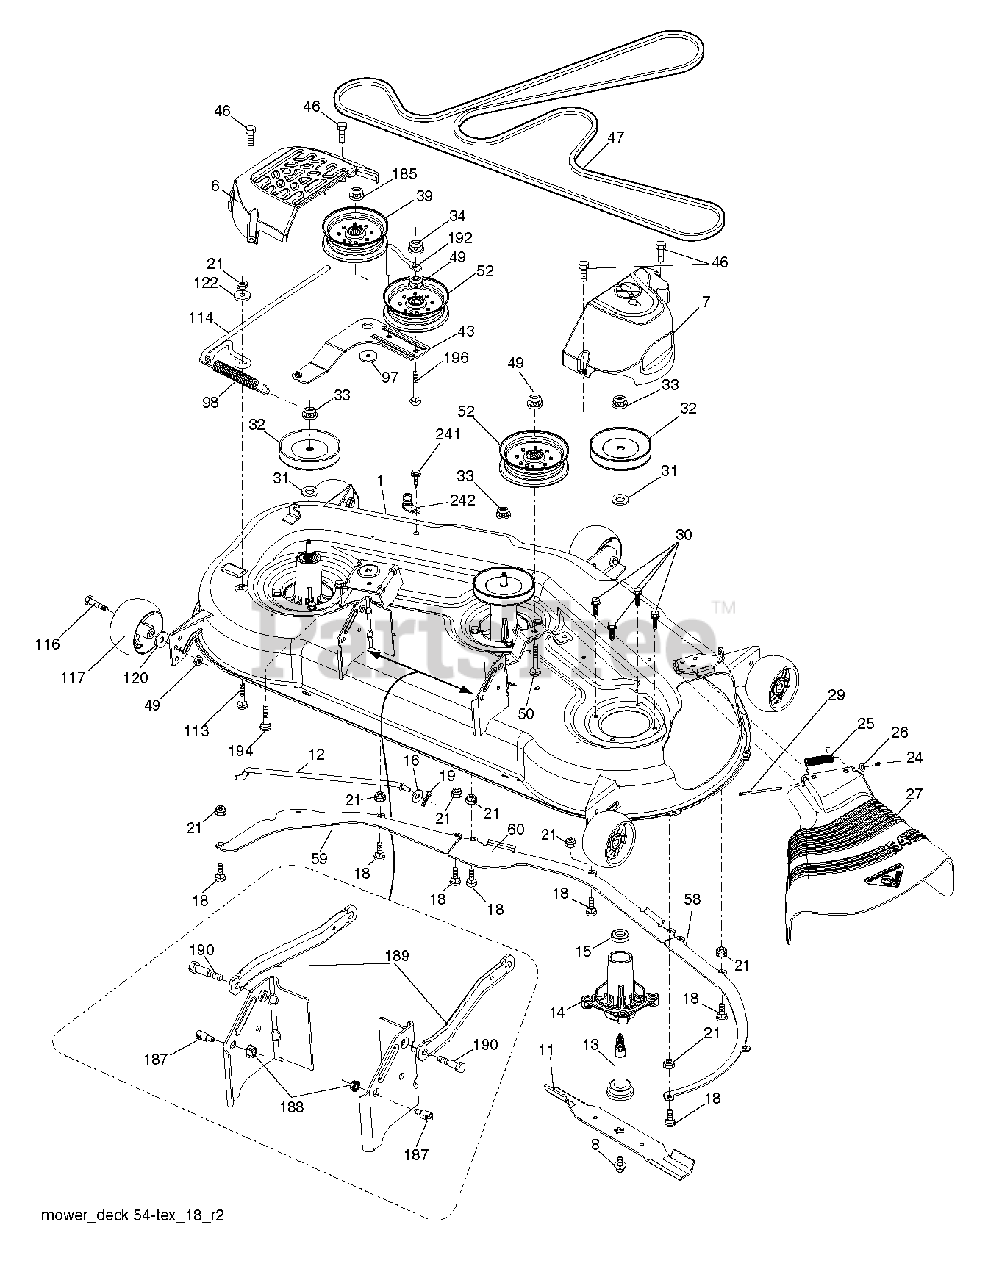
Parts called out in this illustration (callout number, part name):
1	DECK.WELDMENT.54"MS-666
6	COVER.MANDREL.LH.54"20
7	COVER.MANDREL.RH.54.20
8	BOLT.WASHER.ASM.7/16-2
11	BLADE, BAGGING 54"
12	ROD.ANTI.SWAY.48/54"TE
13	SHAFT ASM MANDREL
14	HOUSING MANDREL
15	BEARING
18	BOLT
19	PIN.COTTER.5/16.BOW TI
24	CAP-SLEEVE LT
25	SPRING, TORSION
26	NUT PUSH M
29	HINGE ROD
30	SCREW, WASHER HEAD
33	NUT.FLANGE.LOCK.TOP
34	LOCKNUT
39	PULLEY.IDLER.4.50/HUB SPECIAL
43	ARM.IDLER
46	SCREW 1/4-20X5/8
47	BELT.DRIVE.54."2006
58	BAFFLE.RIGHT.54"
59	BAFFLE LEFT
60	BAFFLE CENTER 54" MOWER
98	SPRING, DECK DRIVE
113	BOLT CRT
114	ROD TENSION RELIEF
116	BOLT.SHOULDER.3/8-16X3-5/8
117	WHEEL. GUAGE RALLY
120	WASHER
122	BUSHING
185	NUT.LOCK.FLANGE.7/16
187	STUD.FASTNER.W/ANTI-ROTATE
188	NUT LOCK HEX FLANGE 5/16-18
189	ARM.SUSPENSION.MOWER
190	BOLT.SHOULDER
192	KEEPER.BELT.IDLER.54"T
242	PORT.WASHOUT
